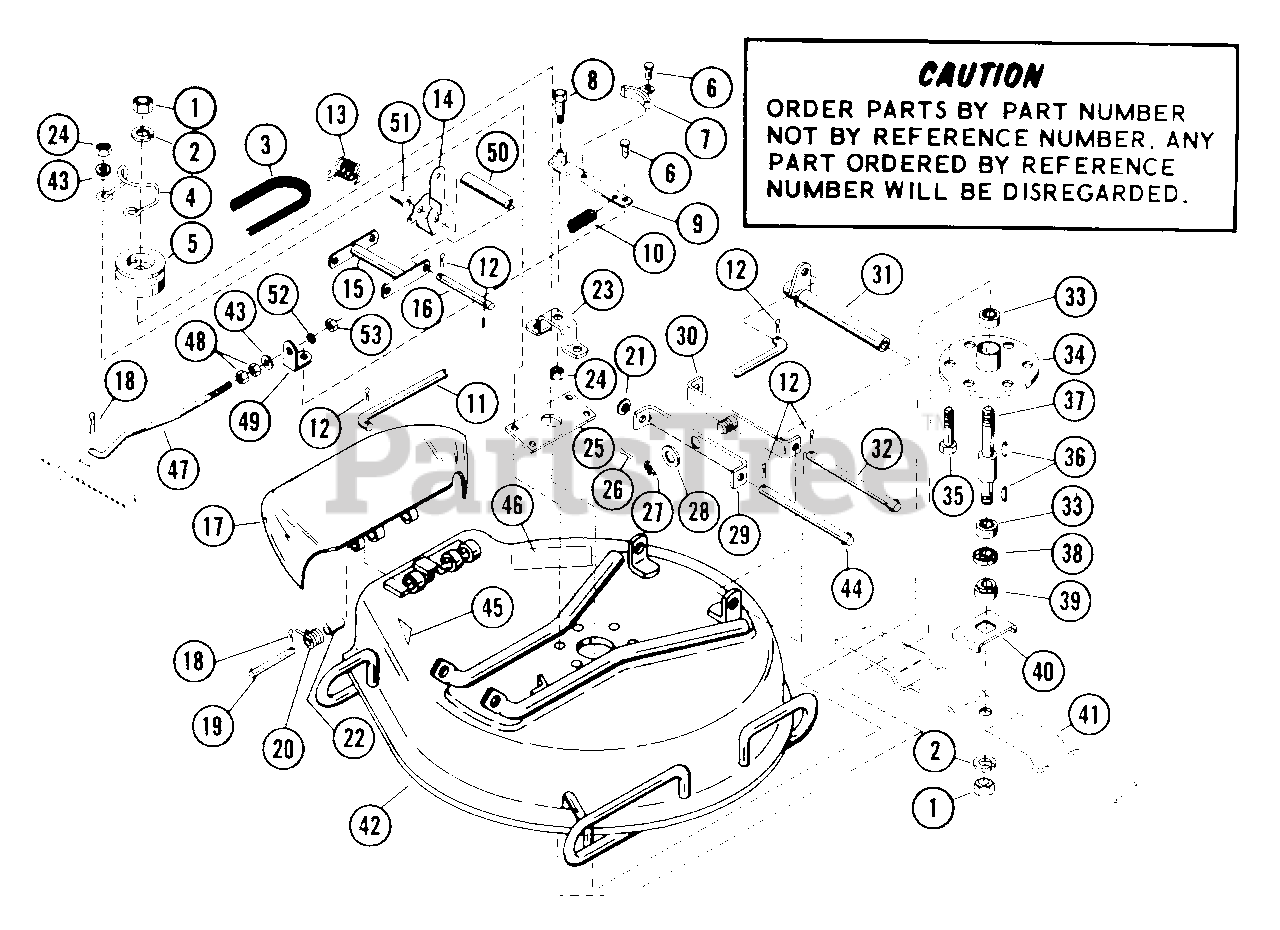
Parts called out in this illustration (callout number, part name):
1	NUT-JAM .75-10 PL
2	WSHR-LK .750X.188 MED PL
3	V-BELT, 5L-RAW EDGE
4	MOWER BELT FINGER
5	MOWER SHEAVE
6	RVT .25X.50 RH ST
7	BLADE BRAKE
8	SHOULDER BOLT .50 X 1.75
9	BLADE BRAKE ARM
10	SG-TENS .072X.51X5.31 WLD 25
11	HEIGHT LINK ROD
12	PIN-COTR .12X1.0 PL
13	SG-TORS ??X.75X??
14	HEIGHT CONTROL BRACKET
15	FLOATING LINK
16	ADAPTER PIN
17	PAN CHUTE EXTENSION
18	PIN-COTR .09X.75 PL
19	CLEVIS PIN
20	SG-TORS .095X.50X 1.0
21	WSHR-FL-STL .531X1.062X.095 PL
22	BSHG-SLV .334 X .502 X 1.437
23	BLADE BRAKE SUPPORT
24	NUT-LK-CTR .375-16 GR A PL
26	PIN-COTR .12 X 1.25 PL
27	NUT-JAM-SL .625-18
28	WSHR-FL-STL .630X1.005X.062 PL
31	REAR RAISING BRACKET
32	REAR BRACKET PIN
33	BRG-BALL .751X1.78X.61
34	SPINDLE HOUSING
35	BLT-HEX .38-16X1.00 PL
36	KEY-WDRF .188X.75X.313 SAE 9
37	MOWER SPINDLE
38	BEARING SLINGER
39	RETAINER HUB
40	BLADE TRAY
41	BLADE, MOWER
42	MOWER PAN ASSEMBLY
43	WSHR-FL-STL .38X.875X.083 PL
44	HANGER PIN
45	SAFETY LABEL
46	MOWER CAUTION LABEL
47	BLADE BRAKE ROD
48	NUT-HEX .312-18
49	BRAKE ROD GUIDE
50	TUBE
51	TUBE
52	GROMMET
53	NUT-LK .312-18 GR A PL
